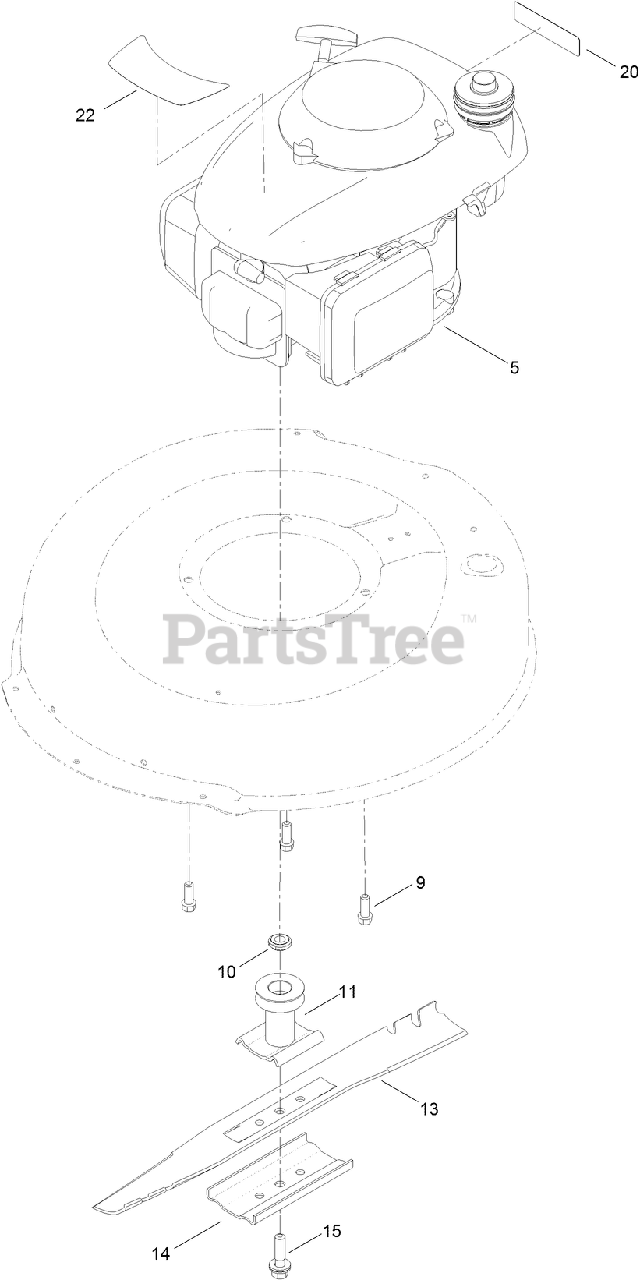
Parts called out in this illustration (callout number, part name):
9	SCREW-TAPTITE
10	SPACER-DRIVER
11	DRIVER-BLADE
14	SUPPORT-BLADE
15	BOLT-BLADE
20	DECAL-ARRESTER, SPARK
22	DECAL-SHROUD
